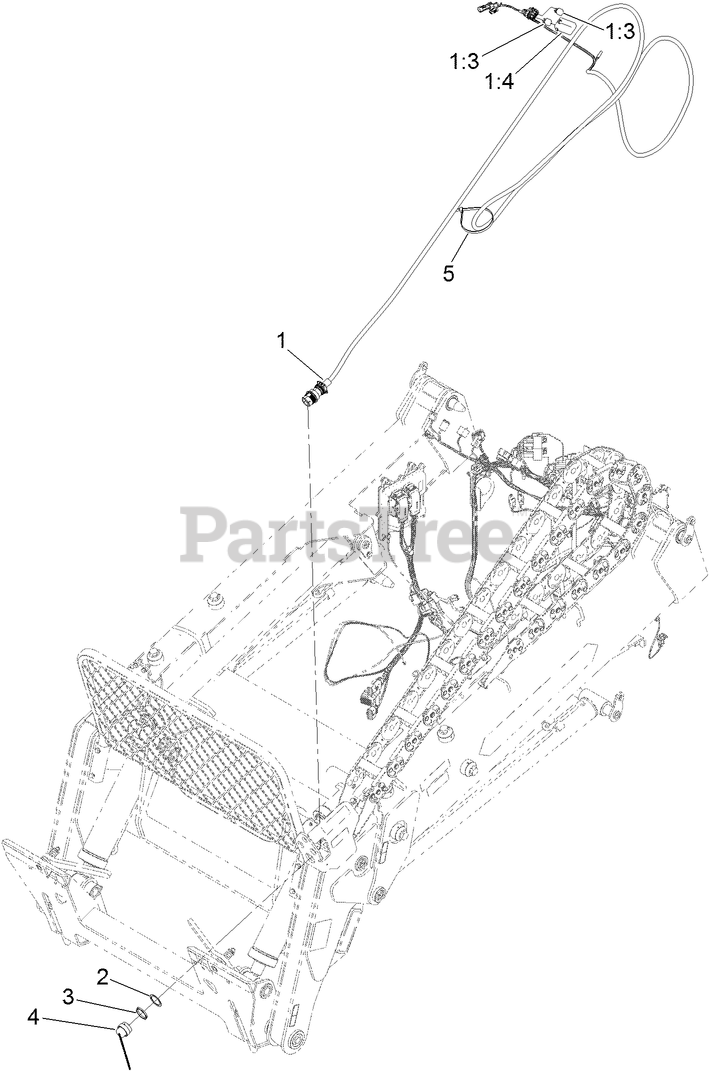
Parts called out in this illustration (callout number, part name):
1	HARNESS-WIRE
1:3	RELAY-MICRO
2	WASHER-LOCK
3	NUT-CONNECTOR
5	TIE-CABLE
